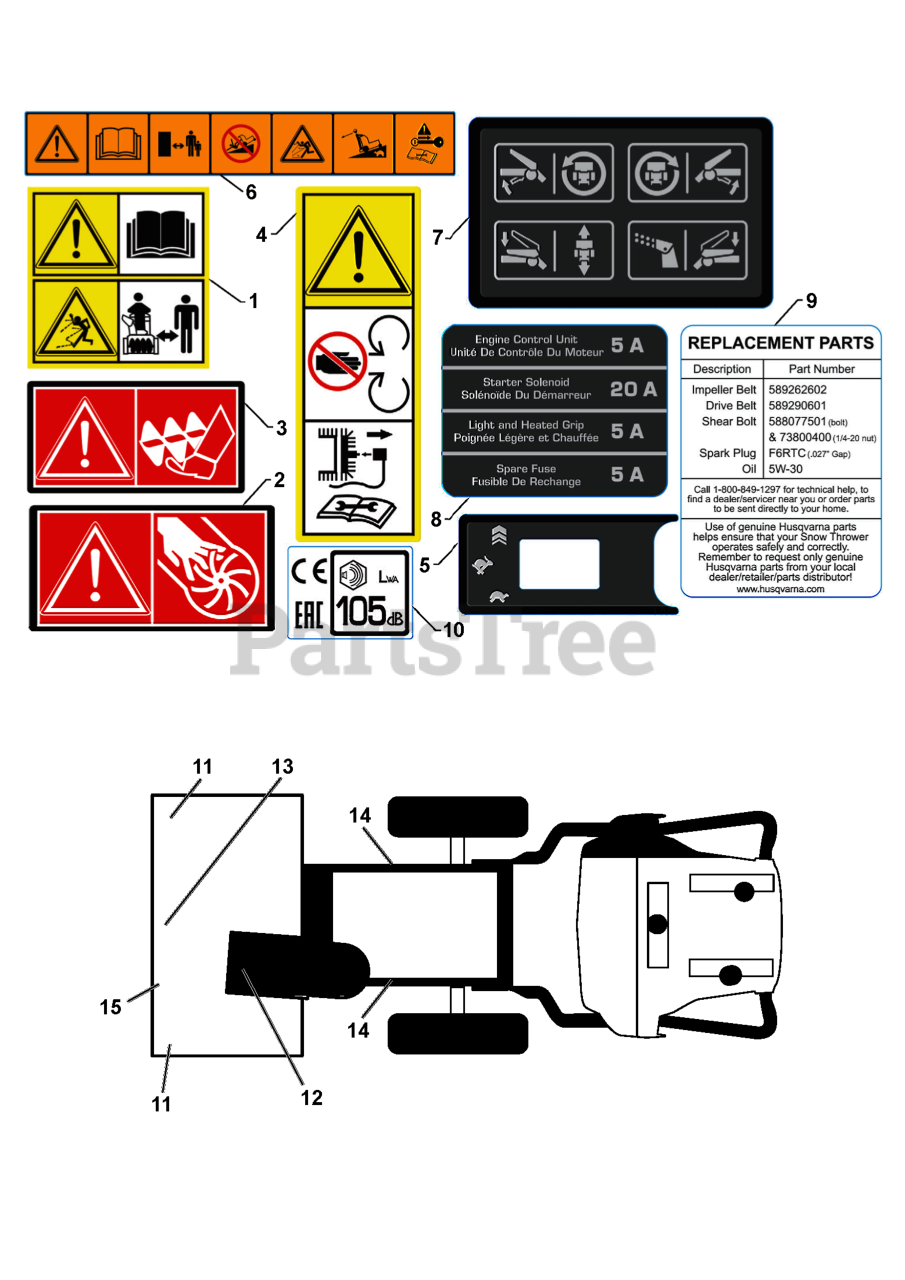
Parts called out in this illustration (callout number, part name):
1	DECAL.AUGER."
2	DECAL.CHUTE.SAFETY.EU/SC.17
3	DECAL.AUGER.SAFETY.
4	DECAL.BELT.GUARD.
5	DECAL SNOW CONSOLE GRAPHIC DEC
6	DECAL SNOW CONSOLE GRAPHIC DEC
7	DECAL SNOW CONSOLE GRAPHIC DEC
8	DECAL SNOW BATTERY BOX GRAPHIC
9	DECAL SNOW BATTERY BOX GRAPHIC
10	DECAL.NOISE.LEVEL.105DB/CE.EAC
11	DECAL.AUGER.SAFETY.
12	DECAL.CHUTE.SAFETY.EU/SC.17
13	DECAL.AUGER."
14	DECAL.BELT.GUARD.
